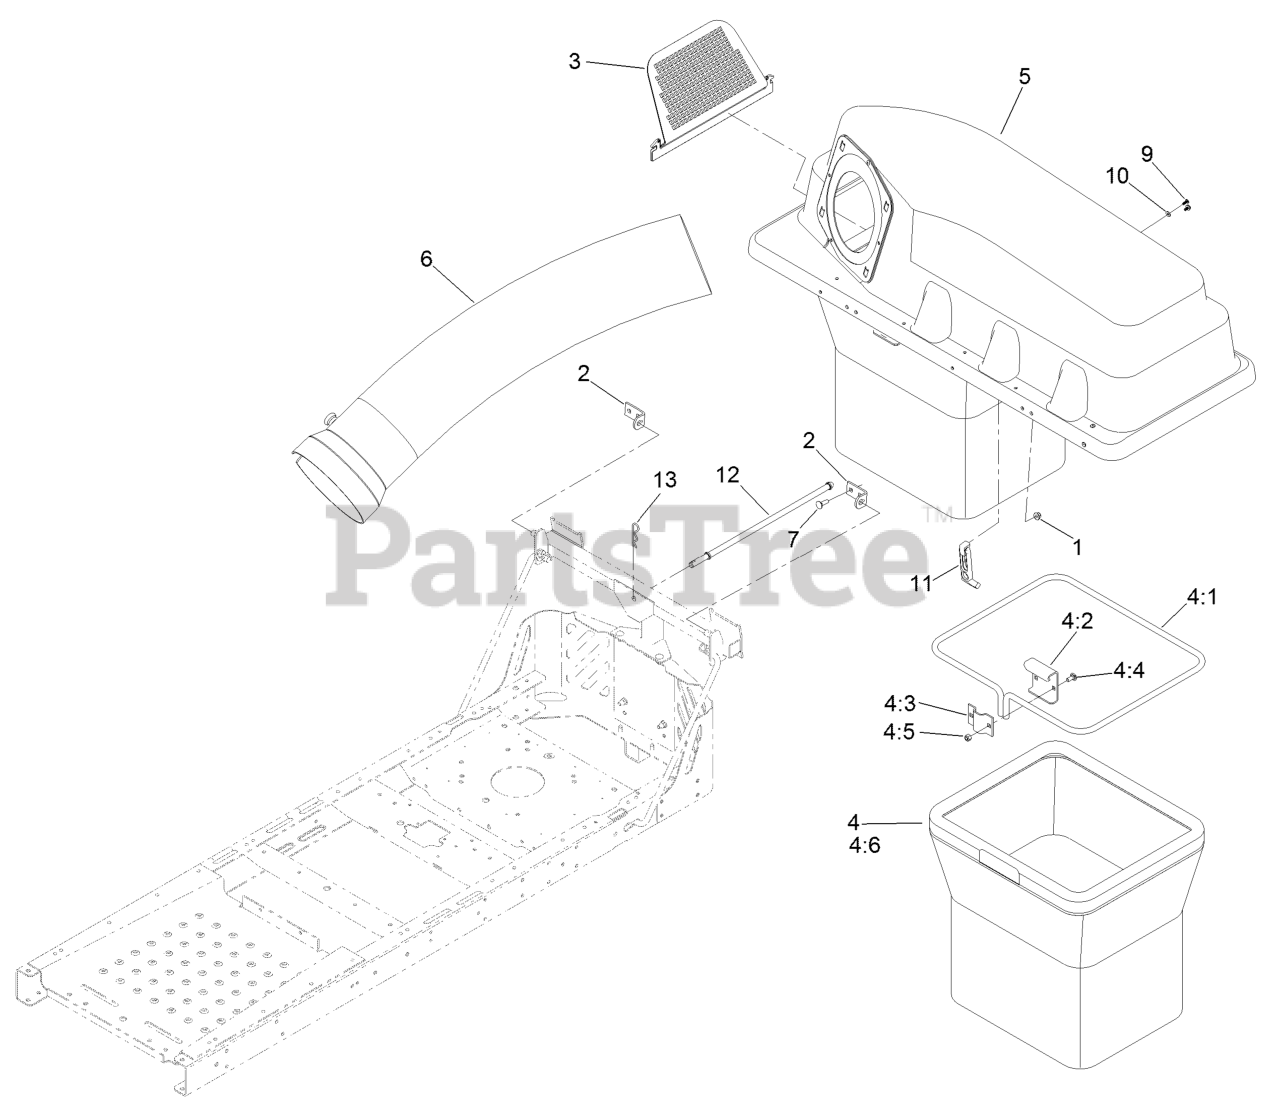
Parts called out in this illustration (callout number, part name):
1	NUT-HF, NI
2	BRACKET-PIVOT, HOPPER
3	SCREEN-BAGGER
4	BAG ASM
4:1	FRAME-BAG
4:2	HANGER-BAG
4:4	BOLT-CARR
4:5	NUT-LOCK, NI
5	BAGGER TOP ASM
6	TUBE-BAGGER
7	BOLT-CARR
9	SCREW-PLASTITE
10	WASHER-FLAT
11	LATCH-RUBBER
12	ROD-HOOD, DOWN (HOLD)
13	PIN-HAIR
